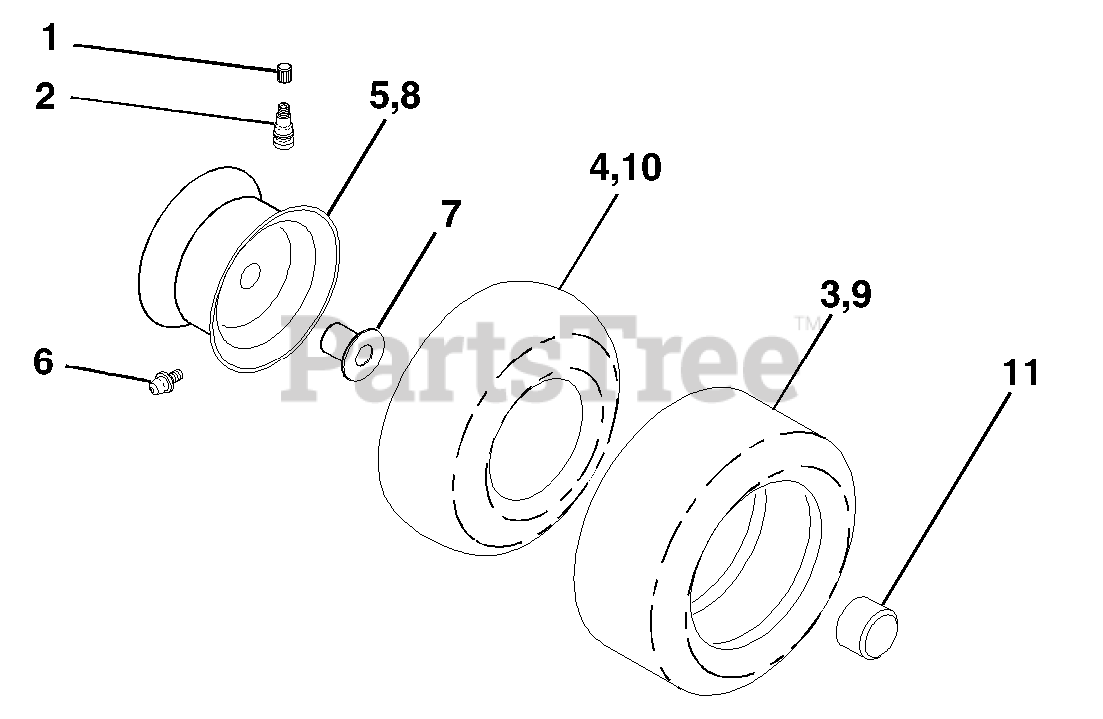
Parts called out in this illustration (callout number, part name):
2	VALVE STEM LT
3	TIRE HEAVY DUTY
4	TUBE.5.3/4.5/6
5	RIM ASM 6" FRONT SILVER
6	FITTING LT
7	BEARING T
8	RIM ASM 8" REAR SILVER
9	TIRE HEAVY DUTY
10	TUBE
11	CAP, AXLE BLK
